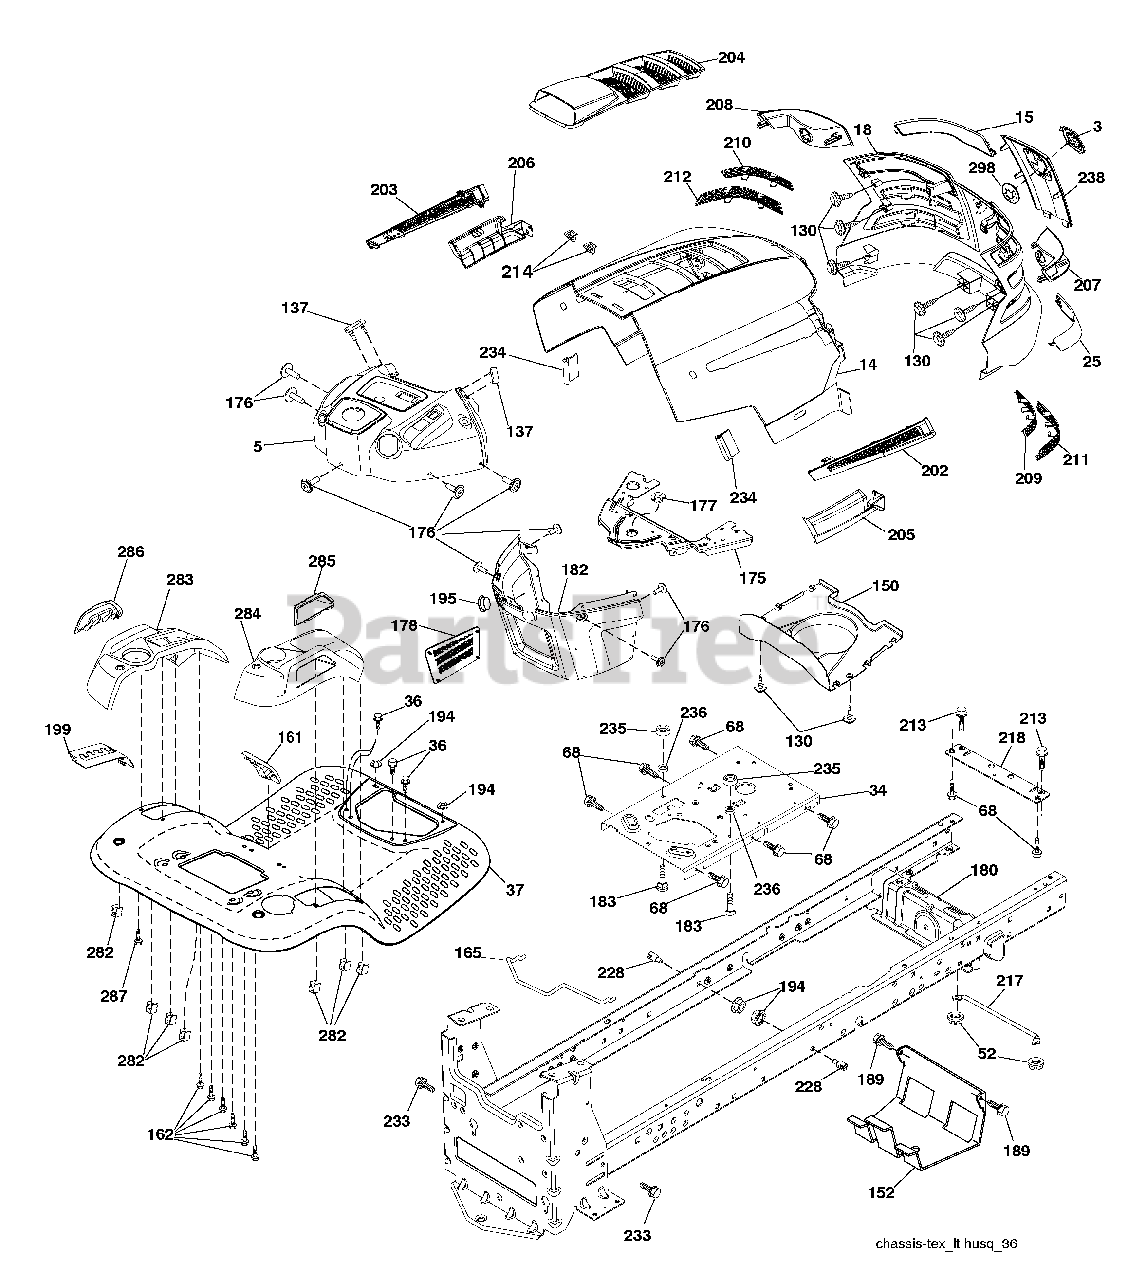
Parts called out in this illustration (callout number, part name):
3	Logo
14	Hood
18	Grille Asm.
34	Plate Engine
36	Screw 5/16-18 x 3/4
52	Nut Lock 5/16-18
68	Screw 5/16-18 x 1/2
130	Screw #10 x 0.750 BOS Thread
137	Bumper Dash
152	Shield Browning
161	Window Fuel
165	Support Tank Rear
175	Crossmember
176	Screw 10-24 x 5/8
177	Bushing Steering
178	Cargo Net Asm.
180	Chassis
181	Bushing Mtg. Fender Crgo
182	Dash Lower
183	Bolt Fin Hex 5/16-18 unc x 1-1/4
189	Screw 5/16-18 x 3/4
194	Nut Lock Hex Flange 5/16-18
195	Plug Hole Dash Lower
199	Plate Deck Lift
202	Vent Side Hood RH
203	Vent Side Hood LH
204	Vent Top Hood
205	Skirt Hood Side RH
206	Skirt Hood Side LH
209	Insert Hex Top RH
210	Insert Hex Top LH
211	Insert Hex Bottom RH
212	Insert Hex Bottom LH
213	Bolt 5/16-18 unc x 3/4
214	Clip Retainer Tinner
218	X-Piece Hood Stop
228	Stud Fastner
233	Bolt Shoulder
234	Bumper Hood
235	Spacer Fender
236	Nut Lock 5/16-18 unc
282	Clip Retainer Console
283	Console Deck Lift
284	Console Asm. Pedal Control
285	Console Insert RH
286	Console Insert LH
287	Screw Hex Washead 1/4-20 x 3/8
